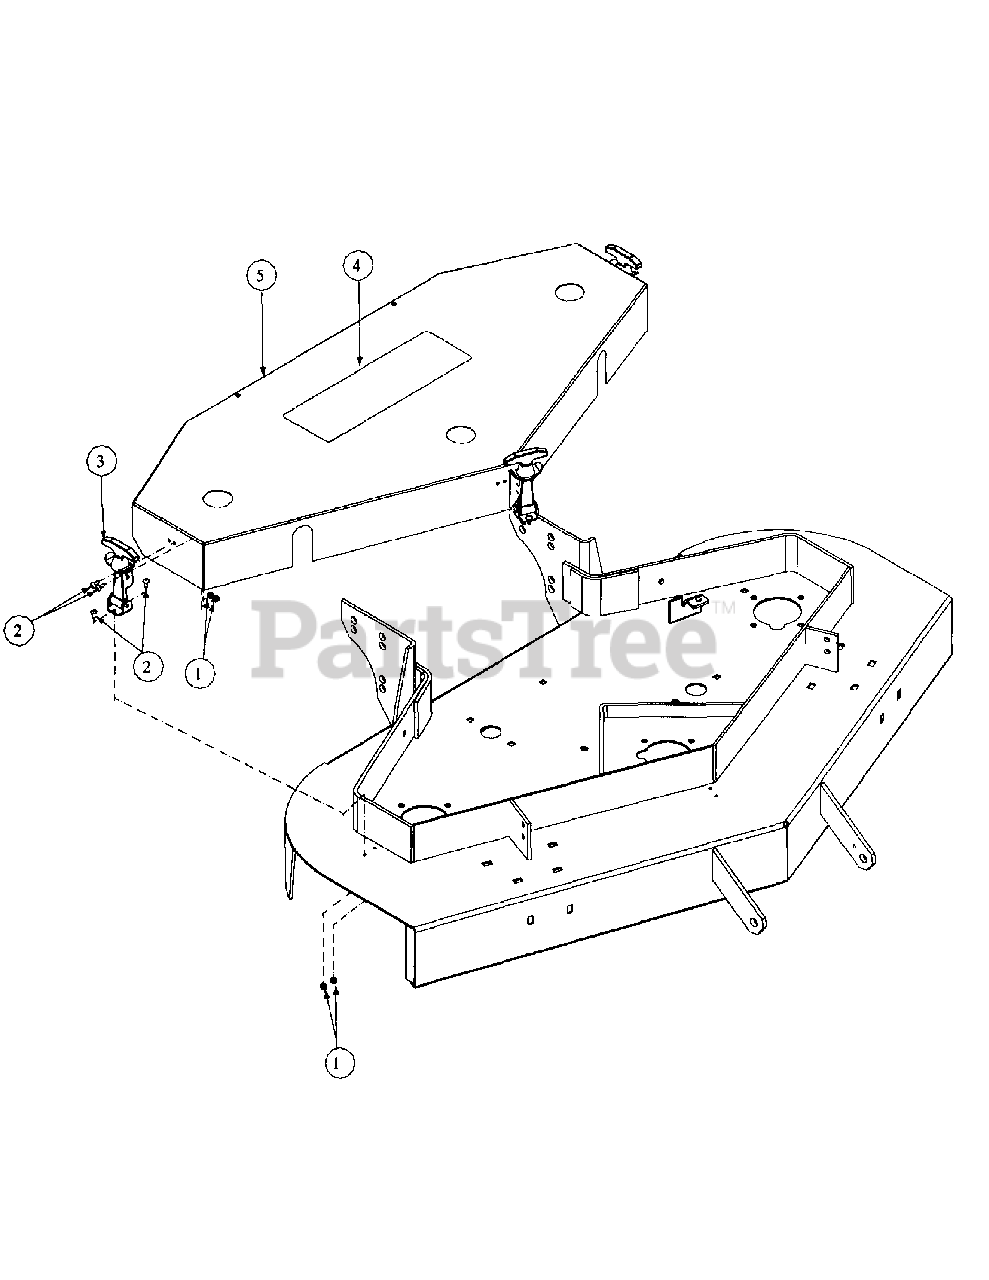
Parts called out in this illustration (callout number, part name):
1	Lock Nut, Nylon Insert, #10-24
2	Machine Screw, 10-24 x 1/2
3	Rubber Hood Latch
4	Decal 52" MTD
5	Cover Assembly, Belt, 52"
